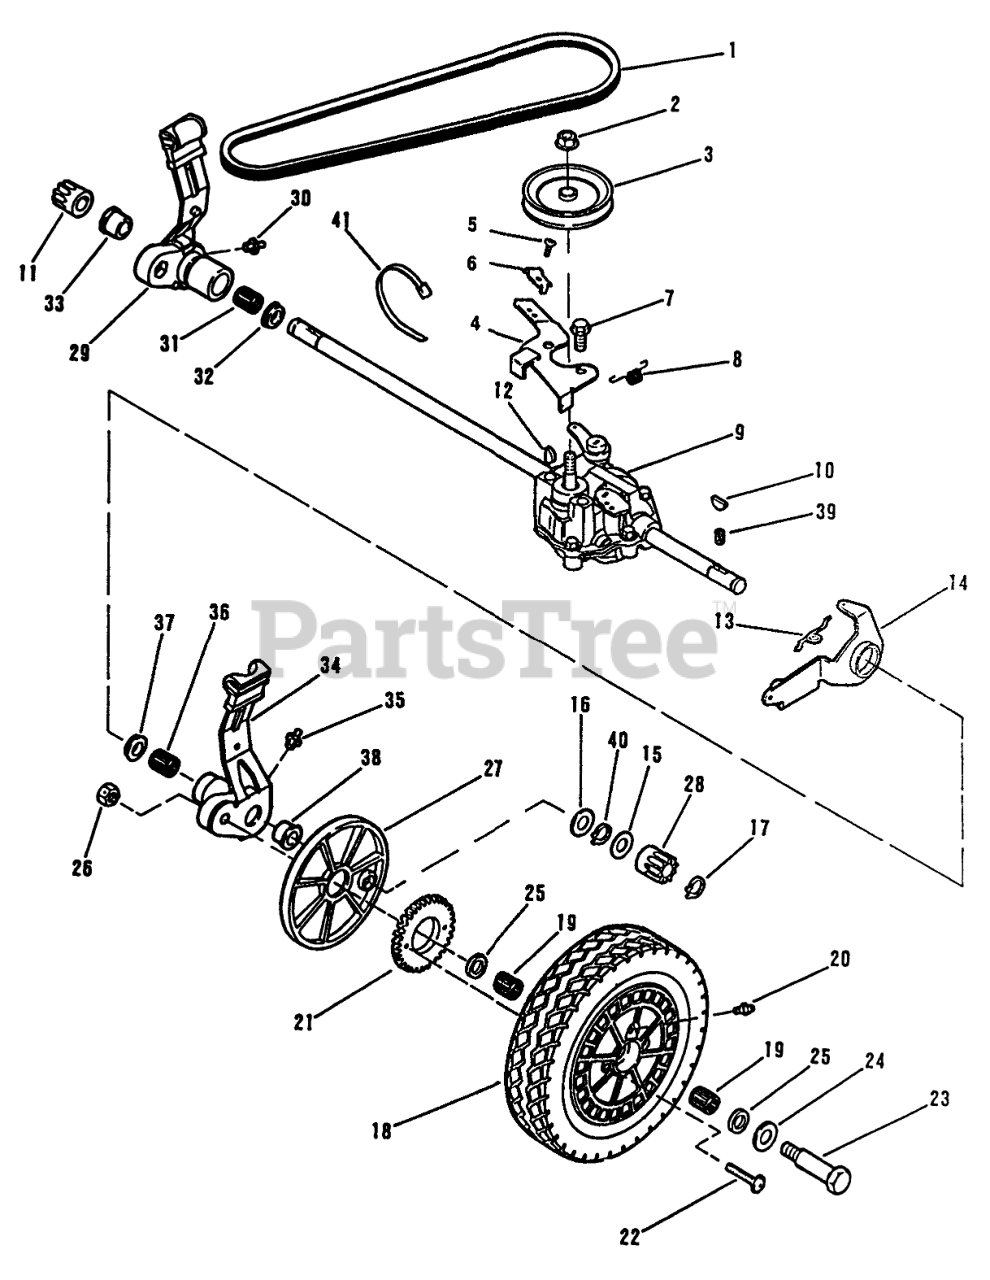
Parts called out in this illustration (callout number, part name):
1	V-BELT
2	NUT-LOCK
3	PULLEY TRANS ADAMS
4	LINKAGE PLATE&SCRW
5	SCREW-CLAMP SM
6	CLAMP-CABLE
7	SCREW SELF TAP
8	SPRING-EXTENSION
9	TRANSMISSION ASSEM
10	KEY
11	PINION(R)MET ALLEG
12	KEY GALGER
13	LINK
14	Actuator Arm and Bushing
15	THRUST WASHER
16	WASHER-THRUST
17	RETAINING RING
18	WHEEL,TIRE&BRG AY
19	Bearing
20	FITTING LINCOLN
21	GEAR
22	SCREW-TORX
23	BOLT WHEEL QUAL
24	WASHER-PLAIN
25	WASHER
26	NUT
27	COVER-WHEEL
28	PINION(L)MET ALLEG
29	Height Adjust Arm Assembly-R.H.
30	FITTING LINCOLN
31	Bearing
32	SEAL CR IND
33	Flange Bearing
34	HT ADJ ARM AY,LEFT
35	FITTING LINCOLN
36	Bearing
37	SEAL CR IND
38	Flange Bearing
39	SPRING
40	RET RING
41	TIE STRAP
